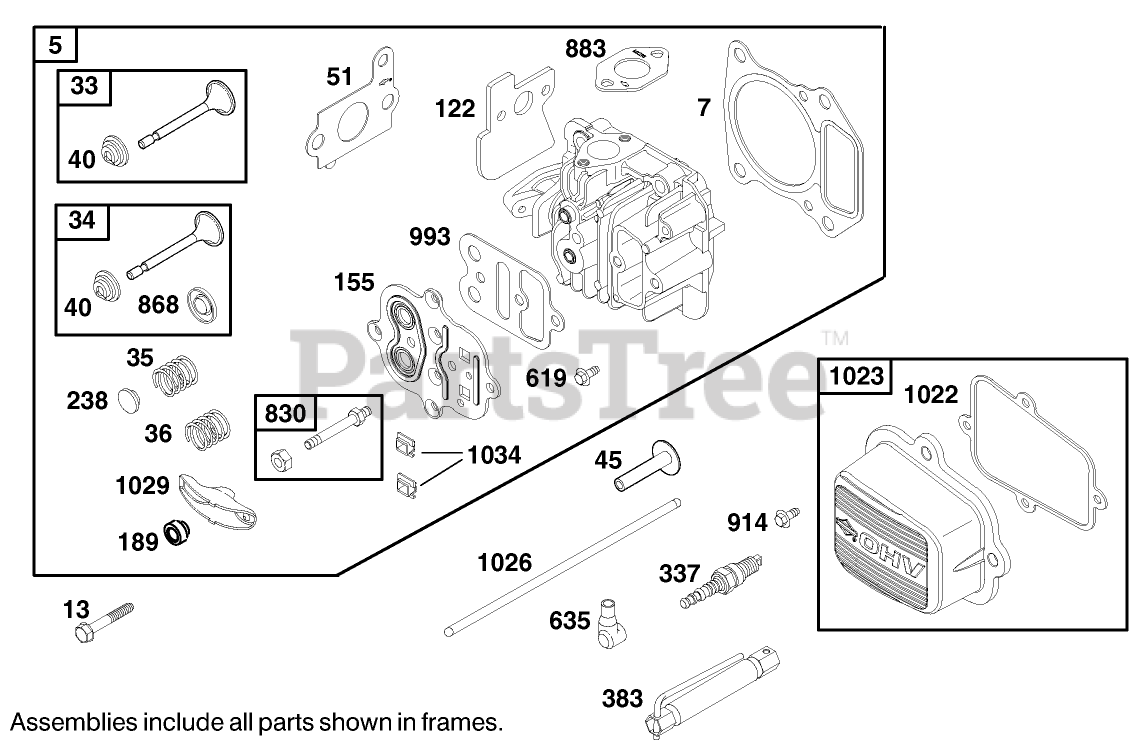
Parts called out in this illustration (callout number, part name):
5	Cylinder Head
7	Cylinder Head Gasket
13	Screw
33	Valve-Exhaust
34	Valve-Intake
35	Spring-Valve
36	Valve Spring (Exhaust)
40	Gear-Cam
45	Tappet-Valve
51	Gasket-Intake
122	Gasket-Intake
155	Cylinder Head Plate
189	Rocker Arm Ball
238	Cap-Valve
337	Sparkplug
383	Wrench-Spark Plug
619	Screw
635	Sparkplug Boot
830	Rocker Arm Stud
868	Valve Seal
883	Exhaust Gasket
914	Screw (Rocker Cover)
993	Plate Gasket
1022	Gasket
1023	Cover?Rocker
1026	Push Rod
1029	Arm-Rocker
1034	Guide-Rod, Push
